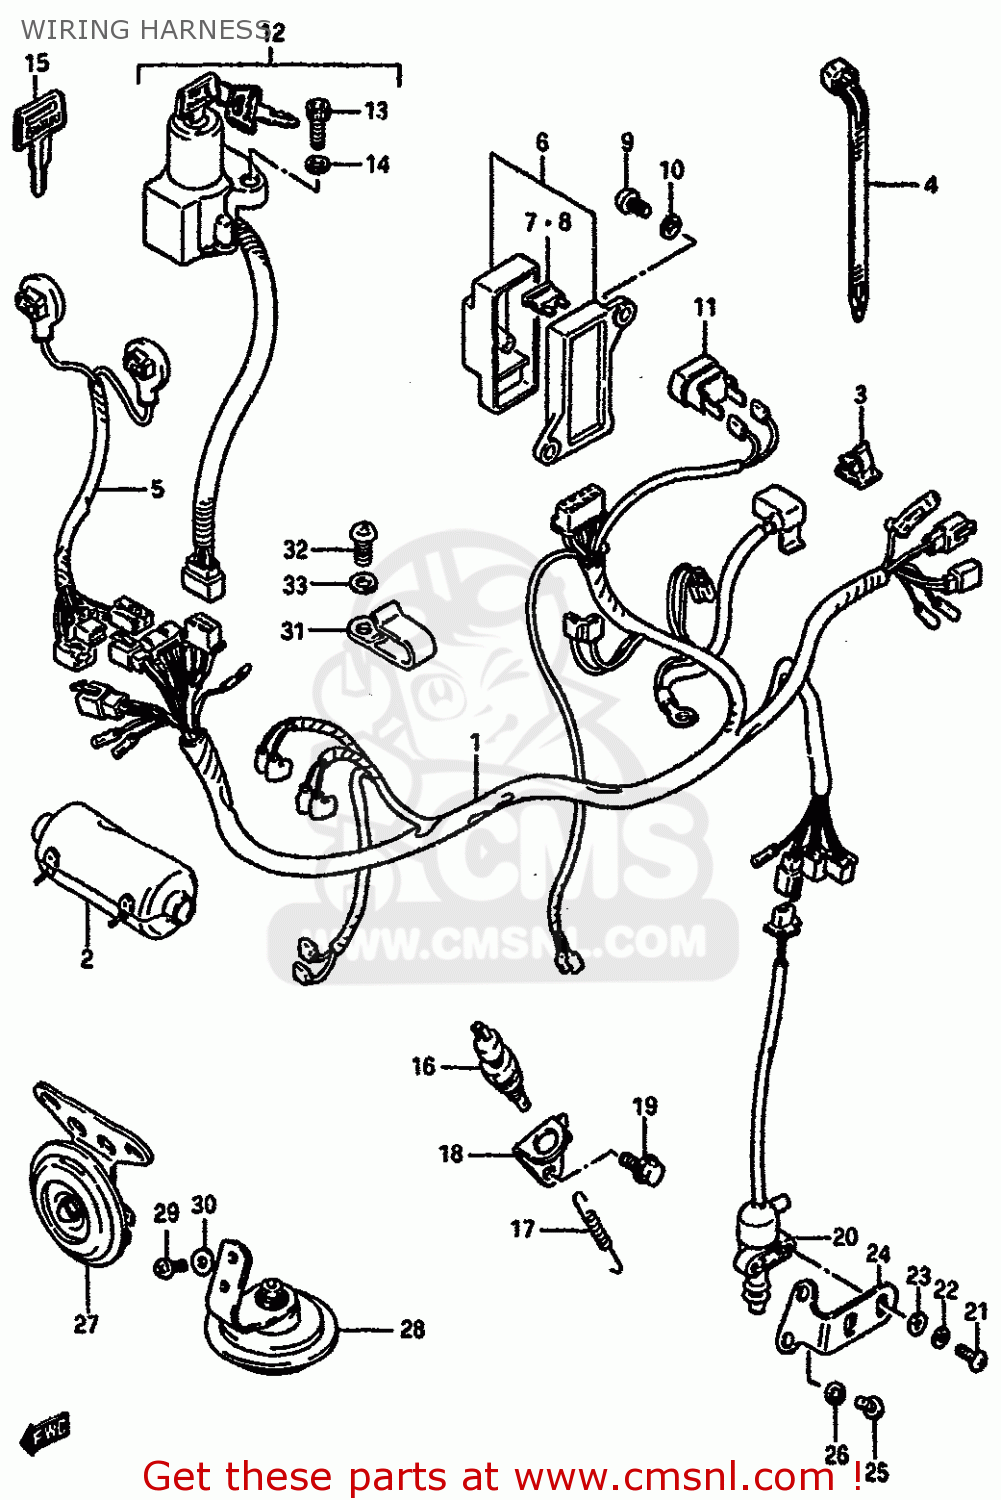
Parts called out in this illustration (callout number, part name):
1	HARNESS,WIRING
2	BOOT,WIRING HARNESS
3	CLAMP
4	CLAMP
5	WIRE,HEADLAMP LEAD
6	BOX ASSY,FUSE
7	FUSE(10A)
8	FUSE(15A)
9	SCREW 6X12
10	WASHER
11	BREAKER ASSY,CIRCUT
12	SWITCH ASSY,IGNITION
13	BOLT
14	WASHER,LOCK
15	KEY,BLANK
16	SWITCH ASSY,STOP LAMP
17	SPRING
18	BRACKET,STOP LAMP SWITCH
19	BOLT
20	SWITCH ASSY,SIDE STAND WARN
21	SCREW 5X20
22	WASHER,LOCK
23	WASHER,5MM
24	BRACKET,PROP STAND WARNING
25	SCREW 6X12
26	WASHER,LOCK
27	HORN ASSY
28	HORN ASSEMBLY
29	SCREW
30	WASHER
31	CLAMP,HANDLE SWITCH
32	SCREW
33	WASHER,LOCK
